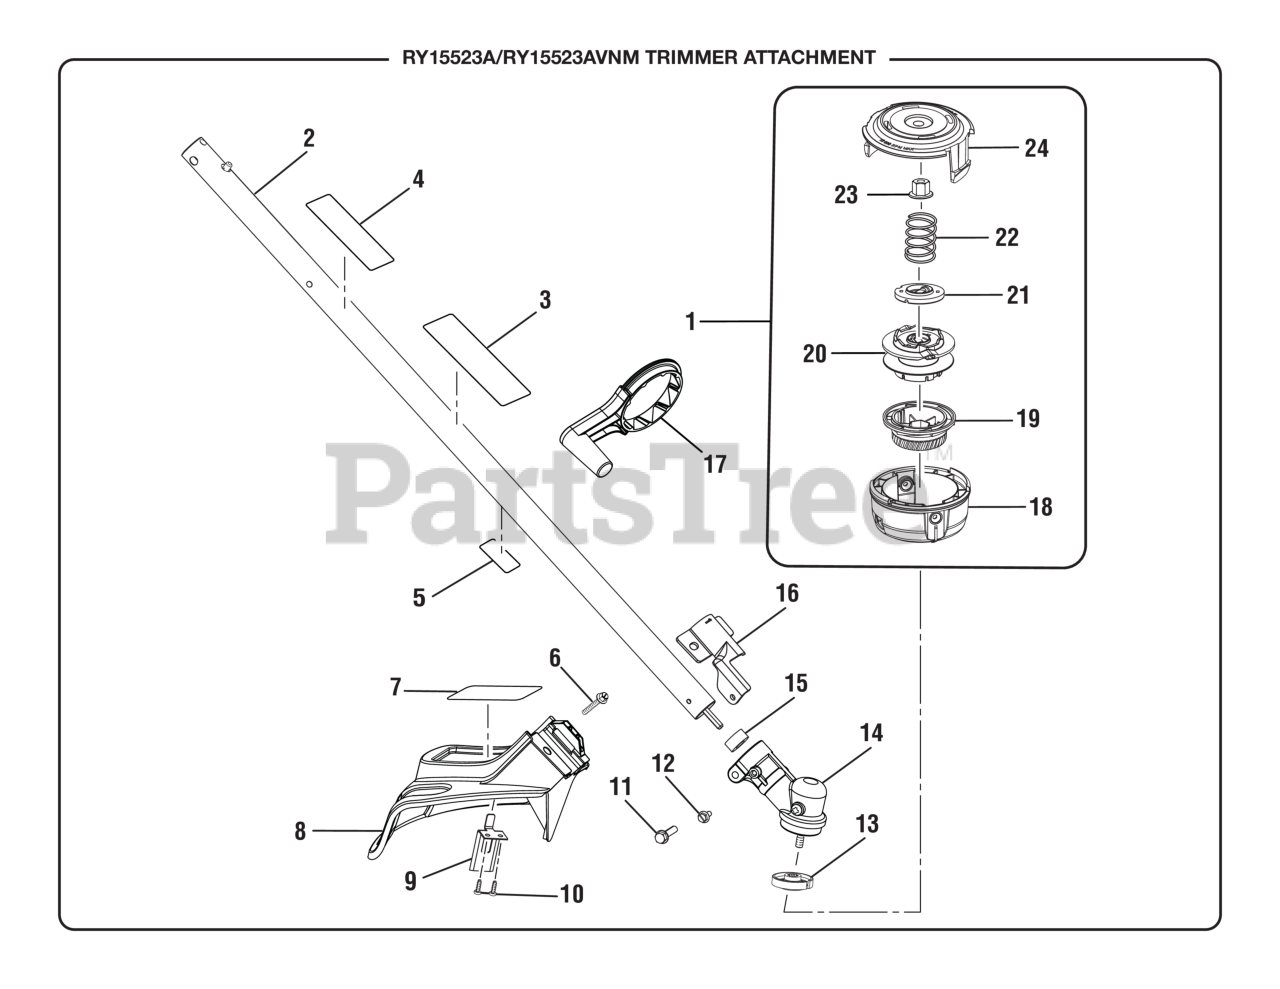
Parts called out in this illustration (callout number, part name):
1	Trimmer Head Assembly (.080)
2	Straight Shaft Assembly
3	Warning Icon Label
4	Ryobi EXPAND-IT Label
5	Data Label
6	SCREW (#1/4-20 X 1-1/4 in. HEX WASHER HD.)
7	Logo Label
8	Grass Deflector Assembly
9	Line Cut-off Blade
11	Screw (1/4-20 x 1-1/4 in., Hex Washer Hd. S.T.)
12	Screw w/Washer (10-24 x 5/8 in., Hex Hd. T.F.)
13	FLANGED WASHER
14	Gear Case Assembly
16	GRASS DEFLECTOR CLAMP
17	Crank Handle
18	Lower Housing
19	Bump Knob (Green)
20	Spool Assembly
21	String Guide
22	Compression Spring
23	Hex Nut (M8, Left Hand Threads)
24	Upper Housing
